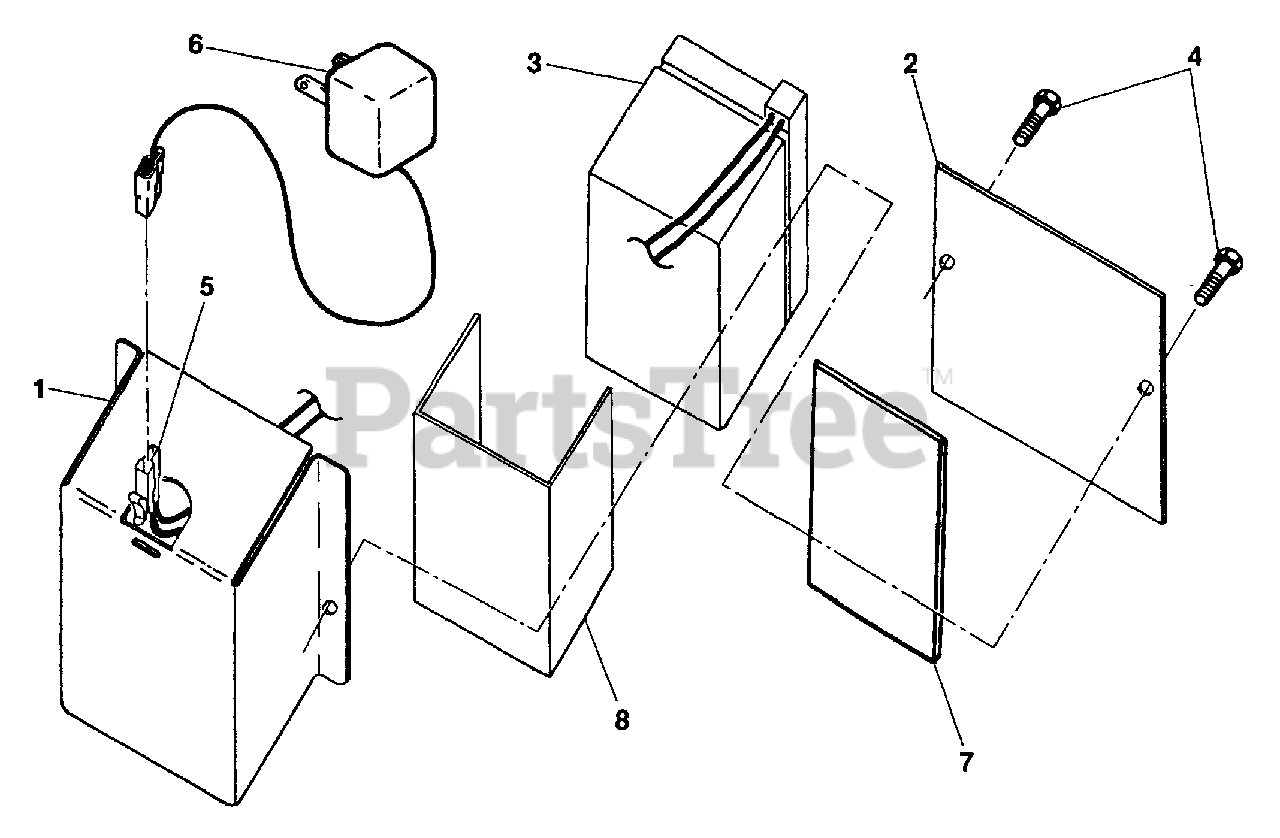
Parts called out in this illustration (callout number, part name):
1	Battery Bracket
2	Battery Cover
3	Battery Kit
4	Hex Washer Head Screw #10-24 x 1/2
5	Connector Mounting Clip
6	Battery Charger
7	Battery Pad
8	Battery Wrap
